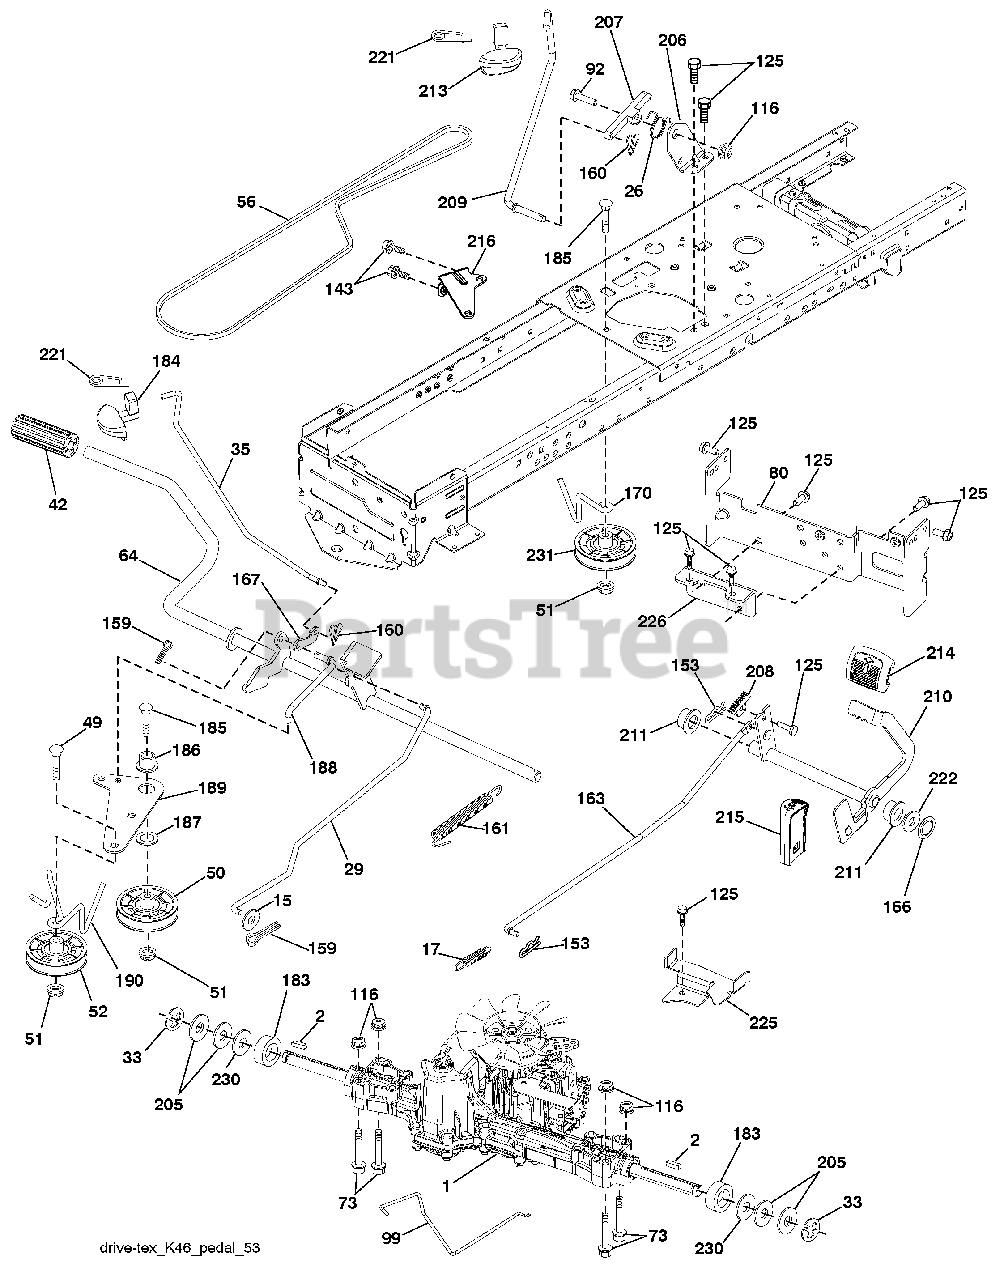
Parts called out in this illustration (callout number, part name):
2	Key
15	Washer 13/32 x 13/16 x 16 Ga.
17	Spring, Brake
26	Spring Return Cruise
29	Rod, Brake
33	Ring E
35	Rod, Brake, Park
42	Cover, Foot Pedal
49	Bolt
50	Pulley Idler Flat
51	Lock Nut 3/8-16
52	Idler V-Groove 910" Offset
56	V-Belt, Drive
64	Shaft Asm. Pedal Brake Control
73	Bolt Hex 5/16-18 x 3.75
80	Strap Torque
92	Bolt Fin Hex 5/16-18 unc x 1.25
99	Rod Spring Bypass
116	Nut Lock Hex Flange 5/16-18
125	Screw 5/16-18 x 3/4
143	Screw 5/16-18 x 1/2
153	Retainer Spring
159	Pin Cotter 1/8 x 3/4
160	Retainer Clip
161	Spring, Return, Clutch
163	Rod Pedal Control
166	Nut Push .625
167	Latch Brake Parking
170	Keeper Belt Centerspan
183	Spacer Axle
184	Handle Parking Brake
185	Bolt
186	Spacer Retainer
187	Washer
188	Link Clutch Ground Drive
189	Bellcrank Ground Drive
190	Keeper Bellcrank Ground Drive
205	Washer 25/32 x 1-5/8 x 16 Ga.
206	Bracket Mount Latch Cruise
207	Latch Control Cruise
208	Gear Sector Control Cruise
209	Rod Control Cruise
210	Rockr Asm. Pdeal Control
211	Bearing Nylon
213	Knob control Cruise
214	Pad Pedal Forward
215	Pad Pedal Reverse
216	Bracket Pulley Idler
221	Retainer Spring Clip Handle
222	Washer 21/32 x 1-1/4 10 Ga.
225	Keeper Belt Transaxle
226	Bracket Mount Torque
230	Washer Harden .793 x 1.637 x 060
231	Idler V-Groove
